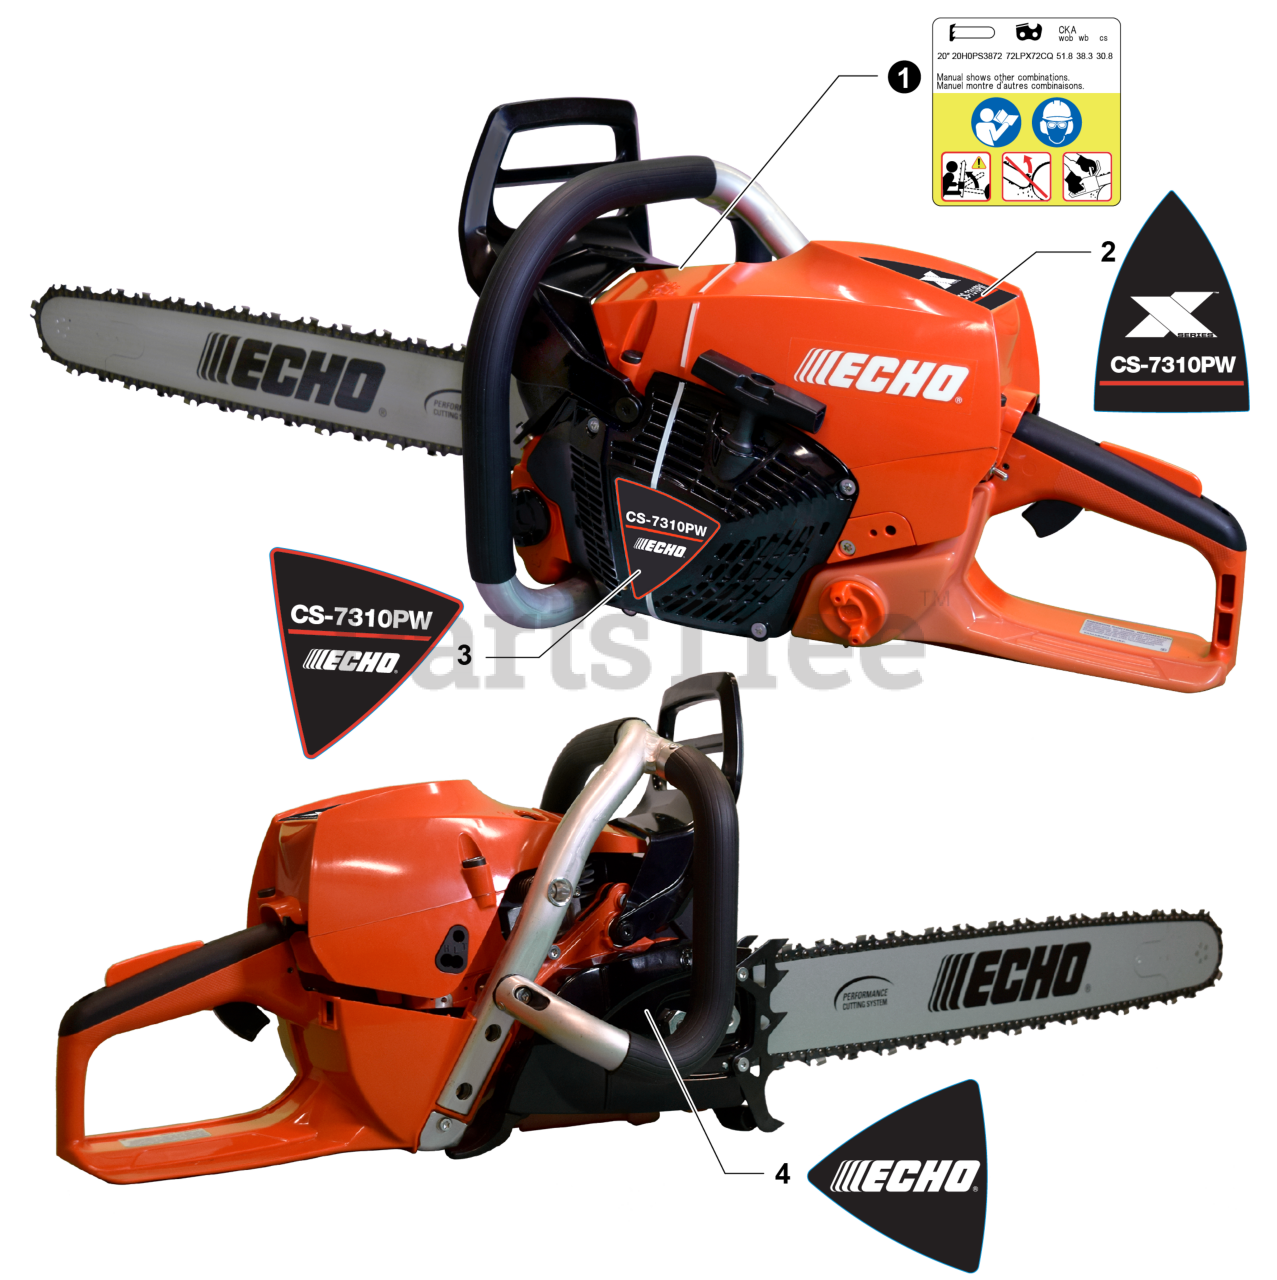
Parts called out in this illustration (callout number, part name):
1	LABEL - CAUTION - ISO
2	LABEL - MODEL CS-7310PW
3	LABEL - RECOIL STARTER
4	LABEL - ECHO
